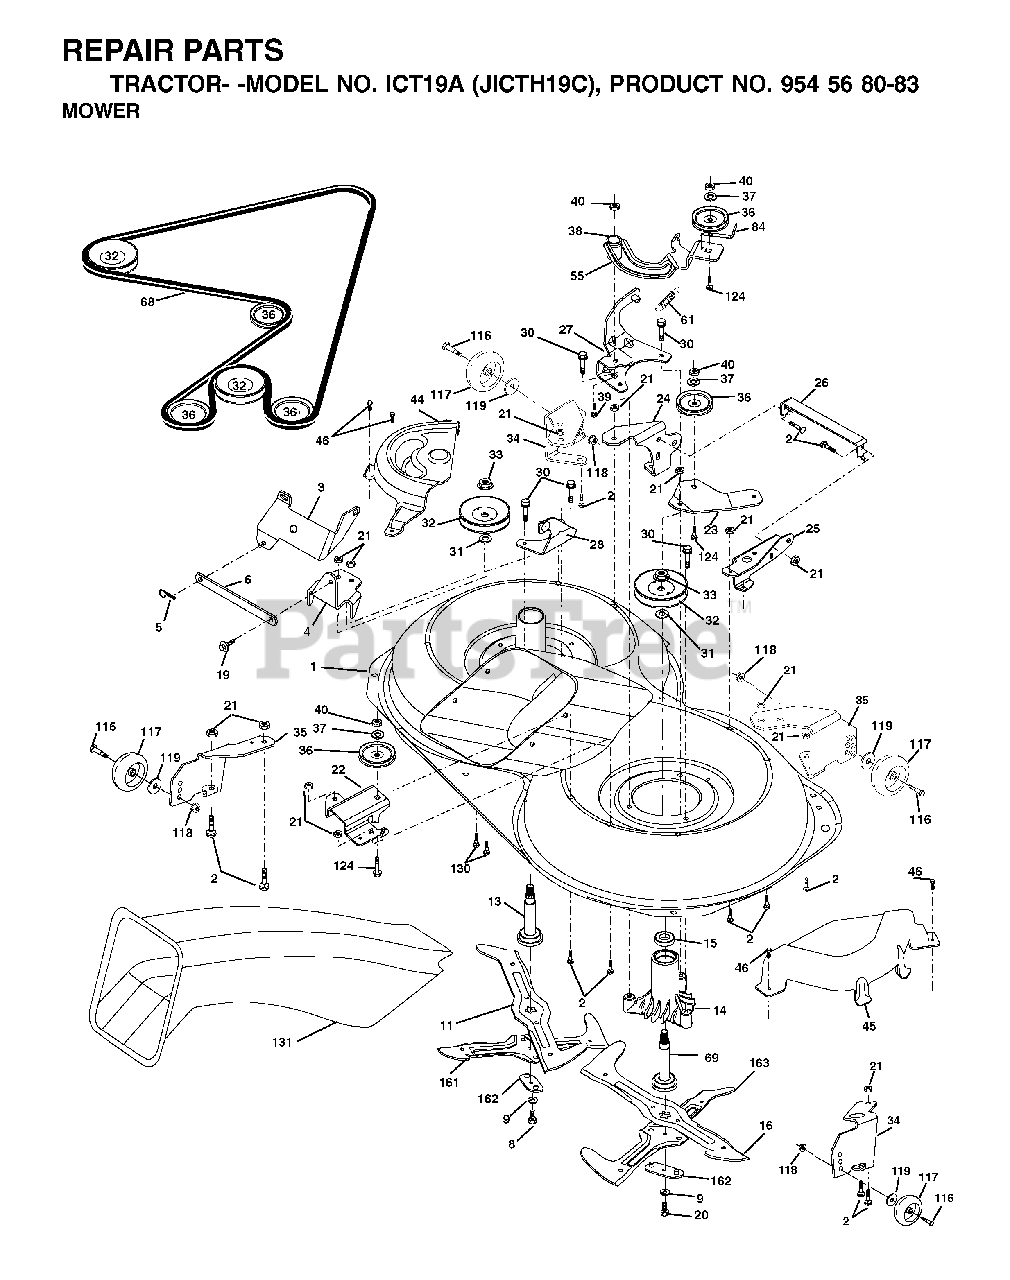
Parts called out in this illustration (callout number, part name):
2	BOLT
3	BRACKET
5	RETAINER-SPRNG RB
6	BAR SWAY
9	LOCKWASHER
11	BLADE.3N1.LH.CRD
13	SHAFT ASM VENT
14	HSG MANDREL
16	BLADE.3N1.RH.CRD
19	BOLT SHD 5/16-18
21	LOCKNUT
22	BRACKET
23	BRACKET
26	BRACE
27	BRACKET
30	SCREW, WASHER HEAD
31	WASHER
33	NUT, FLG TOPLOCK 9/16"
36	PULLEY.IDLER.4.25
40	LOCKNUT
45	MANDREL COVER
46	SCREW.1/4-20X5/8
55	ARM IDLER
68	HEX-BELT 107 MOWER
69	SHAFT.ASM.W/LWR.BRG.RH.THREAD
84	KEEPER, BELT IDLER
116	BOLT, SHOULDER
117	WHEEL GAGE DONUT
118	LOCKNUT
119	WASHER
124	BOLT.3/8-16X1.50
131	CHUTE BAGGER
